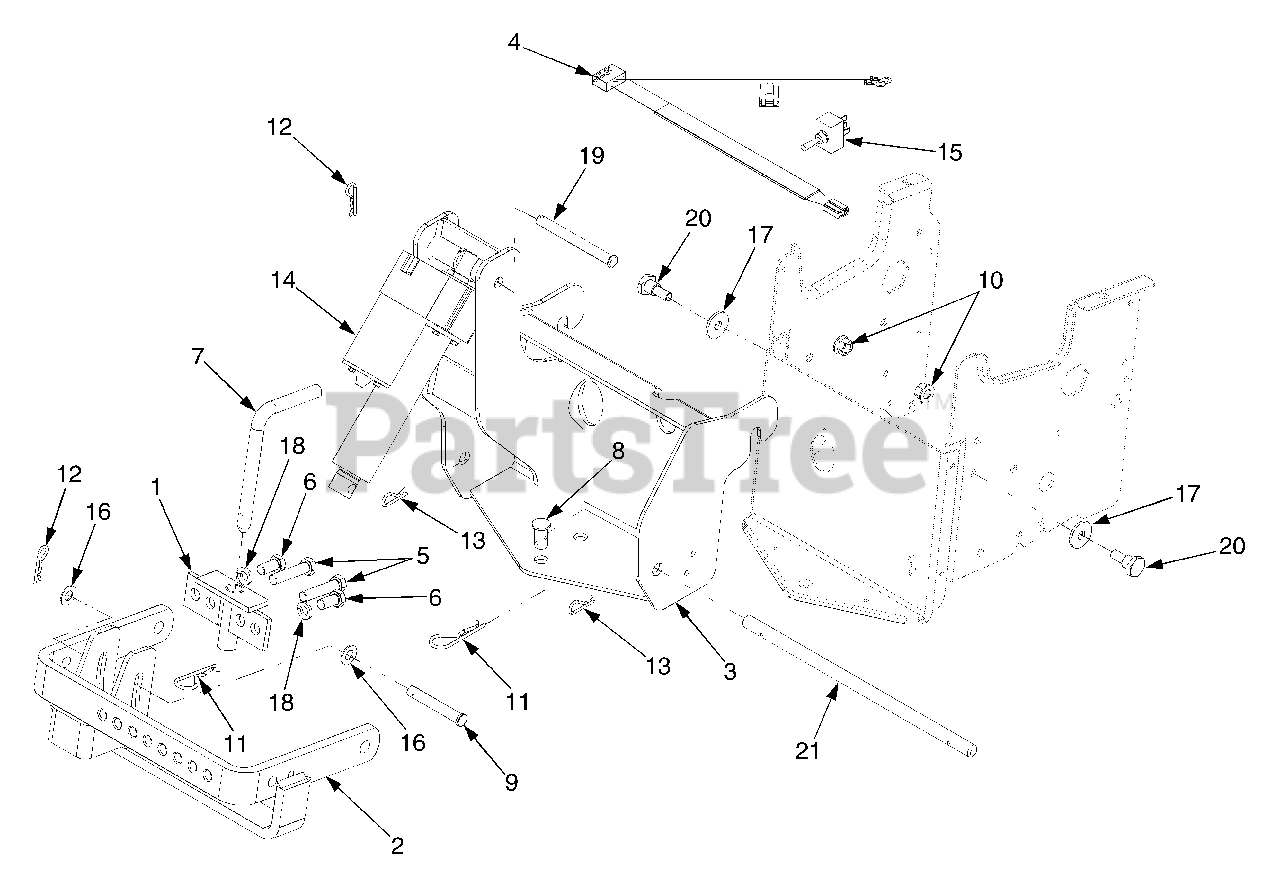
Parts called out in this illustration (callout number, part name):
5	Screw, Hex Cap, 1/2-13 x 2.25 GR5
6	Screw, Hex Cap, 1/2-13 x 1.0 GR5
7	Pin, Hitch
8	Pin, Clevis, .62 Dia
9	Pin, Clevis
10	Nut, Hx Flange Lock, 7/16-20 GRB
11	Pin, Internal Cotter
12	Pin, Internal Cotter
13	Pin, Internal Cotter
14	Actuator, Electric Lift
15	Switch, Toggle
16	Washer, Flat, .51 x 1.0 x .06
17	Washer, Flat, .45 x 1.38 x .134
18	Washer, Lock, 1/2
19	Pin, Hinge
20	Screw, Shoulder, .625 x .5:7/16-20
21	Rod, Hitch
